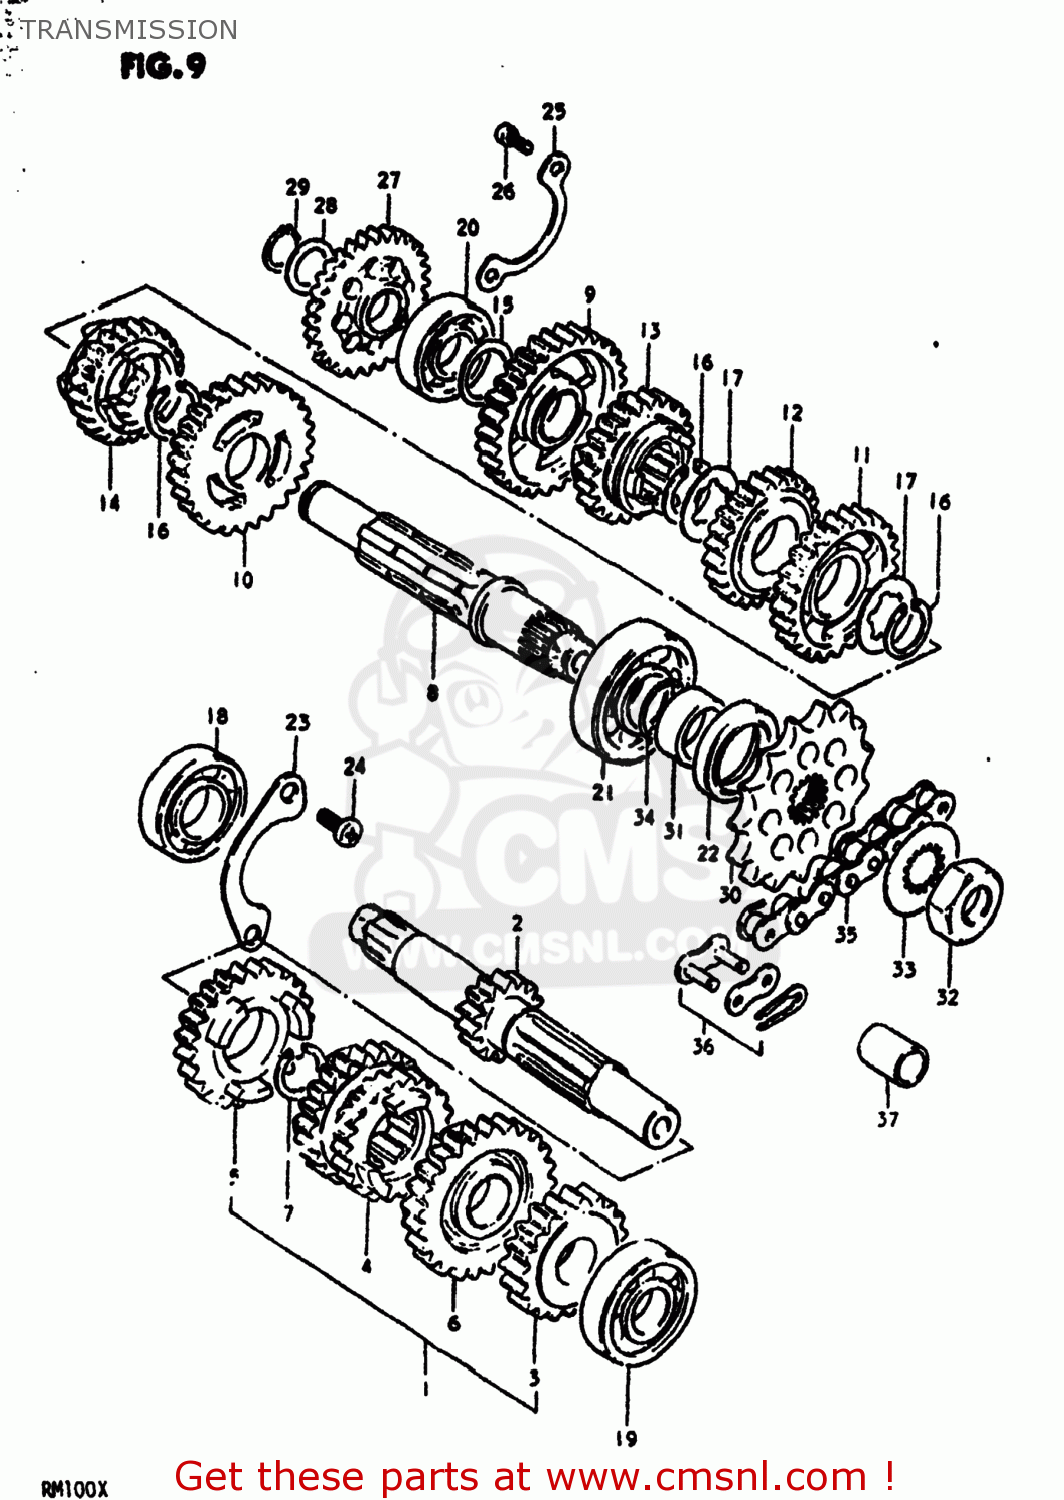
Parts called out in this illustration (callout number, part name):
1	SHAFT,COUNTER
2	SHAFT,COUNTER
3	GEAR,SECOND DRIVE
4	GEAR,THIRD DRIVE
5	GEAR,FIFTH DRIVE
6	GEAR,SIXTH DRIVE
7	CIRCLIP
8	SHAFT,DRIVE
9	GEAR,FIRST DRIVEN
10	GEAR,SECOND DRIVEN
11	GEAR,THIRD DRIVEN
12	GEAR,FOURTH DRIVEN
13	GEAR,FIFTH DRIVEN
14	GEAR,SIXTH DRIVEN
15	WASHER,THRUST
16	CIRCLIP
17	WASHER,LOCK
18	Bearing
19	BEARING
20	BEARING, RH
21	BEARING(20X47X14)
22	SEAL,OIL(25X40X7)
23	RETAINER,CNTR SHAFT BEARING
24	SCREW 6X12
25	PLATE,DRIVESHAFT BEARING
26	SCREW
27	GEAR,KICK STARTER IDLE
28	WASHER,THRUST
29	CIRCLIP,15MM
30	SPROCKET,ENGINE
31	SPACER(20X25X12.5)
32	NUT
33	WASHER,LOCK
34	O RING(D:1,ID:19.5)
35	CHAIN ASSEMBLY,DRIVE
36	JOINT(RK)
37	CUSHION
